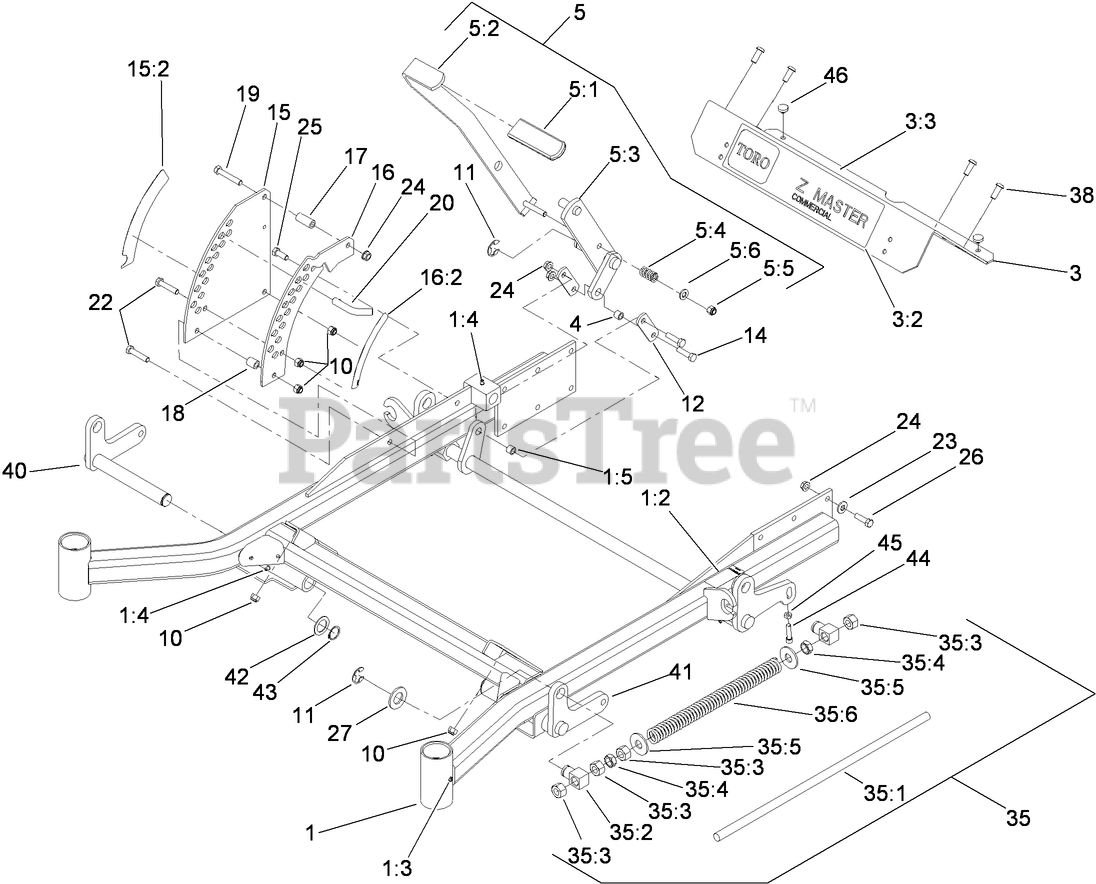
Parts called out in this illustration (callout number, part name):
1	Frame ASM
1:2	Decal-Brake, Parking
1:4	FITTING-GREASE
1:5	Bushing
3	FOOTREST
3:3	DECAL-WARNING
4	Bushing
5	DECK LIFT HANDLE ASM
5:1	GRIP-LEVER, LIFT
5:2	LEVER-LIFT
5:3	ARM-LIFT, DECK
5:4	SPRING-COMPRESSION
5:5	NUT-LOCK, NI
5:6	WASHER-FLAT
10	NUT-LOCK, NI
11	RING-RETAINING, EXT
12	ARM-LIFT, DECK
14	SCREW-HH
15	PLATE-HOC, OUTER
15:2	Decal-Height, Deck
16	PLATE-HOC, INNER
16:2	Decal-Height, Deck
17	BUSHING-LEVER, LIFT
18	BUSHING-LEVER, LIFT
19	SCREW-HH
20	PIN-HOC
22	SCREW-HH
23	WASHER-BELLEVILLE
24	NUT-HHF, WHIZ
25	SCREW-HH
26	SCREW-HH
27	WASHER-FLAT
35	FRONT FRAME SPRING ASM
35:1	ROD-LIFT, DECK
35:2	SWIVEL-DECK MOUNT, REAR
35:3	NUT-HEX
35:4	NUT-JAM
35:5	WASHER-FLAT
35:6	SPRING-SUPPORT, DECK
38	SCREW-HSBH
40	RH DECK LIFT ASM
41	LIFT-DECK, LH
42	WASHER-SPACER
43	RING-RETAINING
44	SCREW-HSH
45	NUT-JAM
46	BUMPER
